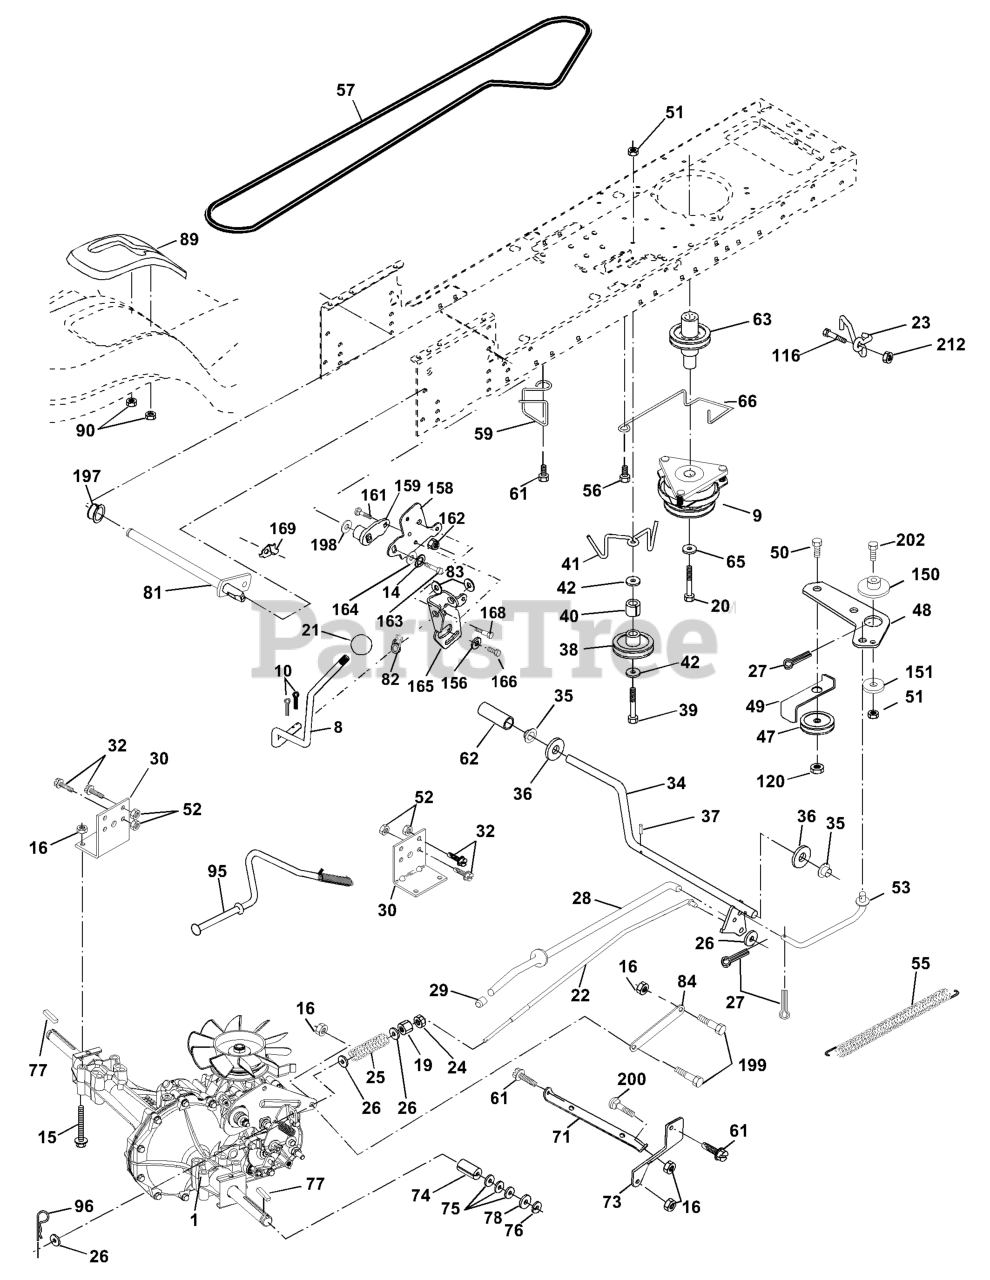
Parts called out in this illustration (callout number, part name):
8	ROD SHIFT FENDER ADJUST STLT
9	CLUTCH, ELECTRIC
10	PIN COTTER
14	LOCKWASHER
15	BOLT HEX 5/16-18 GR 5
16	NUT.71038.31-18.HEX.NYLOCK
19	NUT
20	BOLT HEX 7/16-20X4-1/4"
21	KNOB.DELUXE.(PISTOL.GRIP).BLAC
22	ROD BRAKE HYDRO
23	BRKT ASM MTNG
24	NUT
25	SPRING ROD LT
26	WASHER
27	COTTER PIN
28	ROD, PARKING BRAKE
29	PLUNGER CAP
30	BRKT, TRNSXLE MNT 20"
32	BOLT
34	SHAFT, FOOT PEDAL
35	BEARING.NYLON
36	WASHER LT
37	DRIVE PIN
38	PULLEY.FLAT
39	BOLT
40	SPACER, SPLIT
41	KEEPER, BELT IDLER
42	WASHER
47	IDLER PULLEY
48	BELLCRANK, CLUTCH
49	RETAIN BELT
50	BOLT
53	LINK, CLUTCH LT
55	SPRING, RETURN LT
56	SCREW THDROL 3/8-16 X 1-1/2
57	DRIVE BELT, LTH & YTH TRACTORS
59	KEEPER, BELT CENTER
61	SCREW 3/8-16X3/4
62	PEDAL COVER T
63	PULLEY, ELEC CLUTCH
65	LOCKWASHER
66	KEEPER BELT ENGINE
71	STRAP TORQUE LH HYDRO
73	STRAP TORQUE RH HYDRO
74	SPACER AXLE
77	SQUARE KEY
81	SHAFT ASM CROSS TAPERED
82	SHIFT SPRING
83	WASHER
84	LINK TRANSAXLE
89	SHIFT CONSOLE
90	NUT.PUSH.3/16
95	CONTROL ASM. BYPASS HYDRO
96	RETAINER M
116	Bolt Rdhd Sqnk 3/8-16 Unc x 1
120	NUT LOCK FLG 3/8-16 UNC
150	SPACER, RETAINER
151	WASHER 12/32X2X10GA
156	WASHER.SRRTD.5/16
158	BRACKET
159	HUB
161	BOLT
162	NUT.CROWNLOCK.1/4
163	BOLT
164	Washer 5/8 x .281 x 10 Ga
165	RP BRACKET
168	BOLT.SHOULDER.5/16-18X
169	PLATE.FASTENING.CROSS.SHAFT
197	NYLINER SNAP 5/8" ID
198	WASHER.NYL.7/8IDX.105"HYD CR
199	BOLT SHOULDER 5/16-18 UNC
200	BOLT
202	BOLT.3/8-16X1.50
212	NUT
